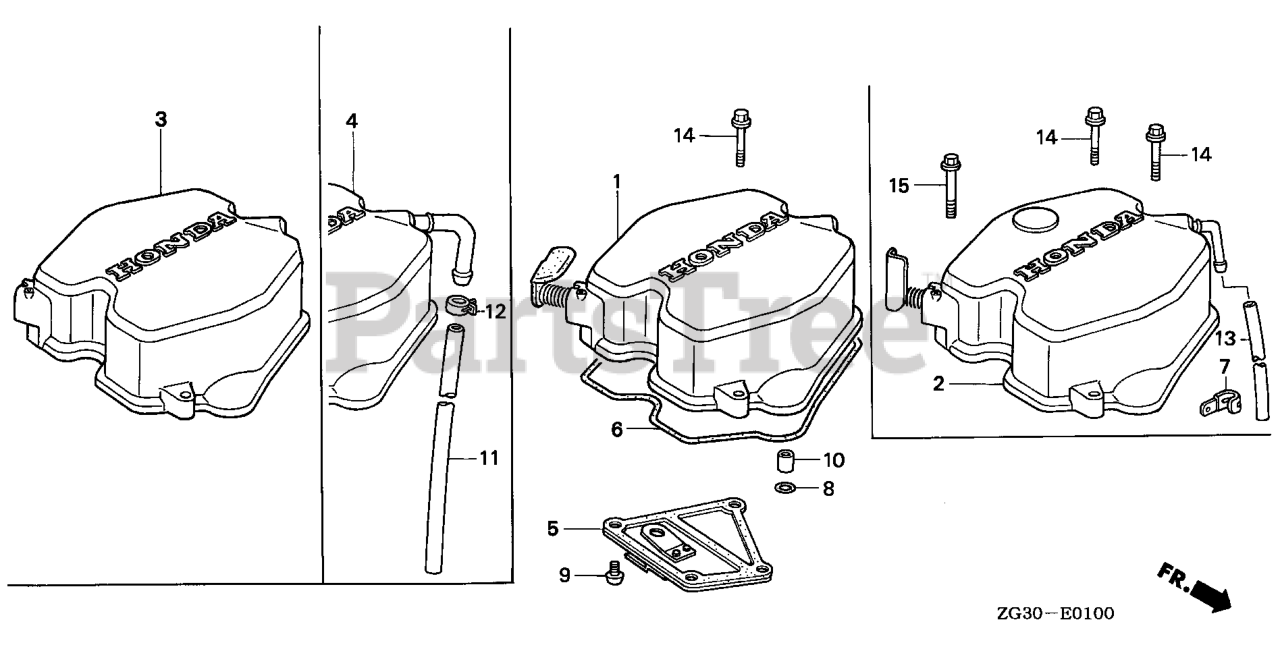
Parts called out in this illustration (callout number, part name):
1	COVER, CYLINDER HEAD (SEL)
5	PLATE, BREATHER
6	O-RING, HEAD COVER
8	O-RING
9	SCREW, PAN (6X8)
10	PIN A, DOWEL (6X10)
14	BOLT, FLANGE (6X32)
